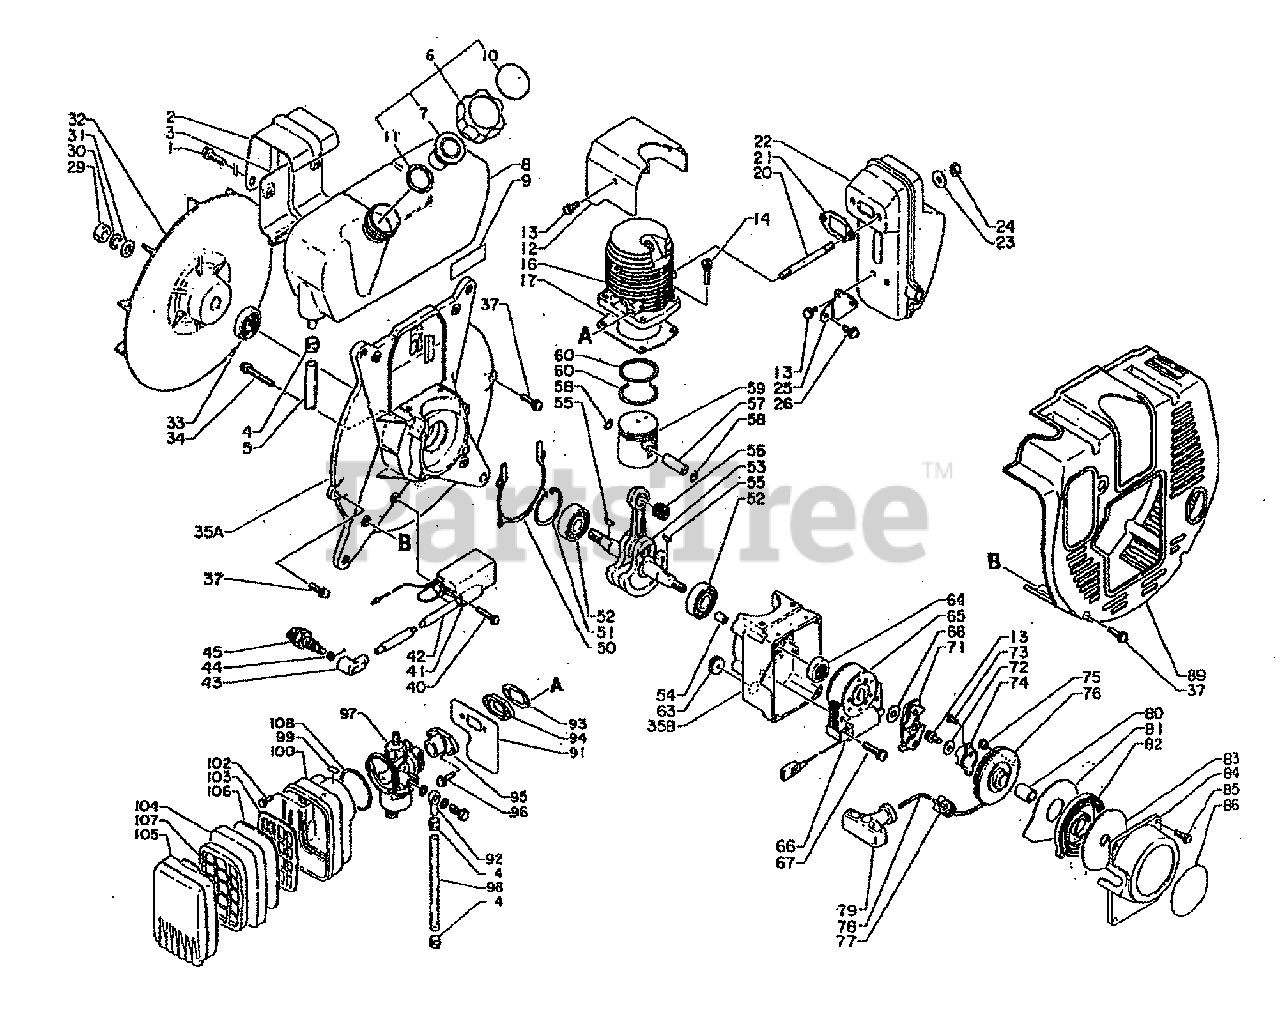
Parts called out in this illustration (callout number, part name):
1	Bolt 6 x 20
2	Bracket, Fuel Tank
3	Bracket, Fuel Tank
5	Pipe 7 x 11 x 360
6	Cap Ass'Y Fuel
7	Greather Cup
8	Tank, Fuel
12	Cover, Cylinder
13	Screw 5 x 10
14	Bolt, H.S.H. 6 x 20
17	Gasket, Cylinder
24	Lock Nut
26	Screw 5 x 14
30	Washer, Spring 10
31	Washer 10
34	Bolt, H.S.H.
35	Crank Case Set
37	Screw 5 x 20
40	Screw 4 x 20
41	Module, C.D.I.
43	Cap, Spark Plug
44	Coil, Plug Cap
45	Plug, Spark
50	Gasket, Crankcase
52	Bearing, Ball
53	Crankshaft Ass'y
54	Pin, Dowel
55	Key, Woodrugg 3
56	Bearing, Needle
57	Pin, Piston
58	Circlip, Piston Pin
60	Ring, Piston
66	Coil, Exciter
67	Screw 5 x 25
71	Ratcher, Ass'y, Starter
73	Screw 4x8
74	Catcher, Pawl
76	Reel, Starter
77	Guide, Rope
78	Rope, Starter
79	Grip, Starter
81	Plate
82	Spring, Rewind
84	Case, Starter
85	Screw 4x16
86	Lable
89	Cover, Engine
91	Gasket, Wind Proof
92	Connector, Pipe
94	Insulator
95	Adaptor, Intake
96	Bolt 6x25
97	Corburator Ass'y
98	Pipe 7 x 11 x 230
99	Lable
100	Case, Air Filter
102	Screw 4 x 14
104	Filter, Air
105	Cover, Air Filter
106	Filter, Air
107	Grid, Air Filter
